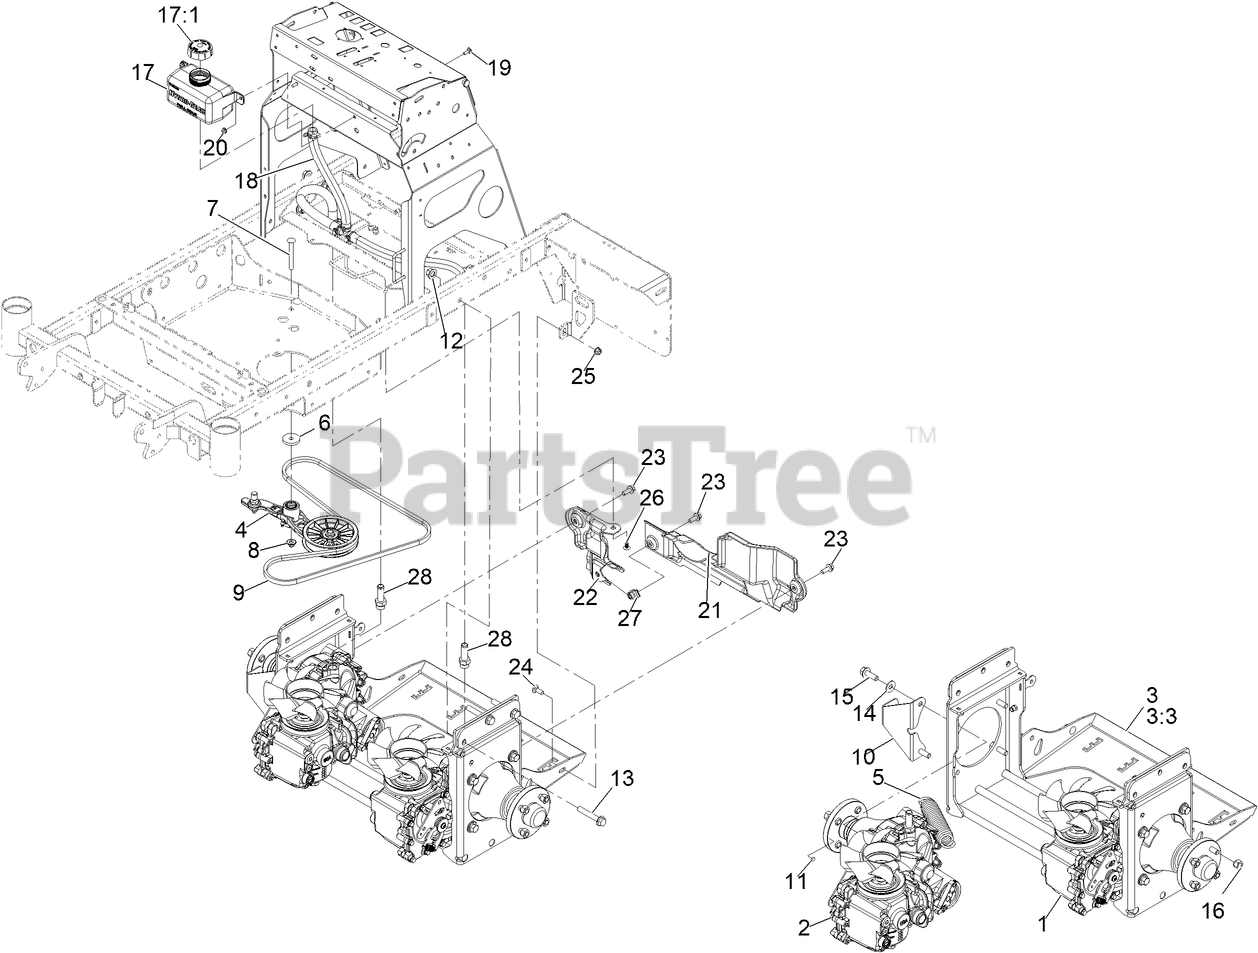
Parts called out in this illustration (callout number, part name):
1	ZT5400-LEFT
2	ZT5400-RIGHT
3	FRAME-ASM, ZT5400
3:3	DECAL-WARNING
4	ASM-PUMP IDLER
5	SPRING-EXTENSION
6	WASHER-PLAIN
7	BOLT-SHOULDER, CARRIAGE 3/8-16 X 3 1/2
8	Nut-Nyloc 3/8-16 Flg
9	BELT-V, COGGED
10	BRACKET-SENSOR, SPEED
11	MAGNET, SPEEDOMETER
12	Nut-Lock 1/2-13
13	SCREW-HF
14	WASHER-SPRING
15	SCREW-HHF
16	NUT-LUG
17	HYDRAULIC RESERVOIR ASM
17:1	CAP-RESERVOIR, HYD
18	ASM-HOSE, EXPANSION
19	BOLT,CARRIAGE,1/4-20X3/4,ST/ST
20	Nut-Hex Flange
21	COVER-REAR, LT
22	COVER-REAR, RT
23	SCREW-HHF
24	SCREW-CARR
25	Nut-Hex Flange
26	PLUG-PLASTIC
27	NUT-TINNERMAN
28	FITTING-STRAIGHT, 5/8 HOSE BARB
